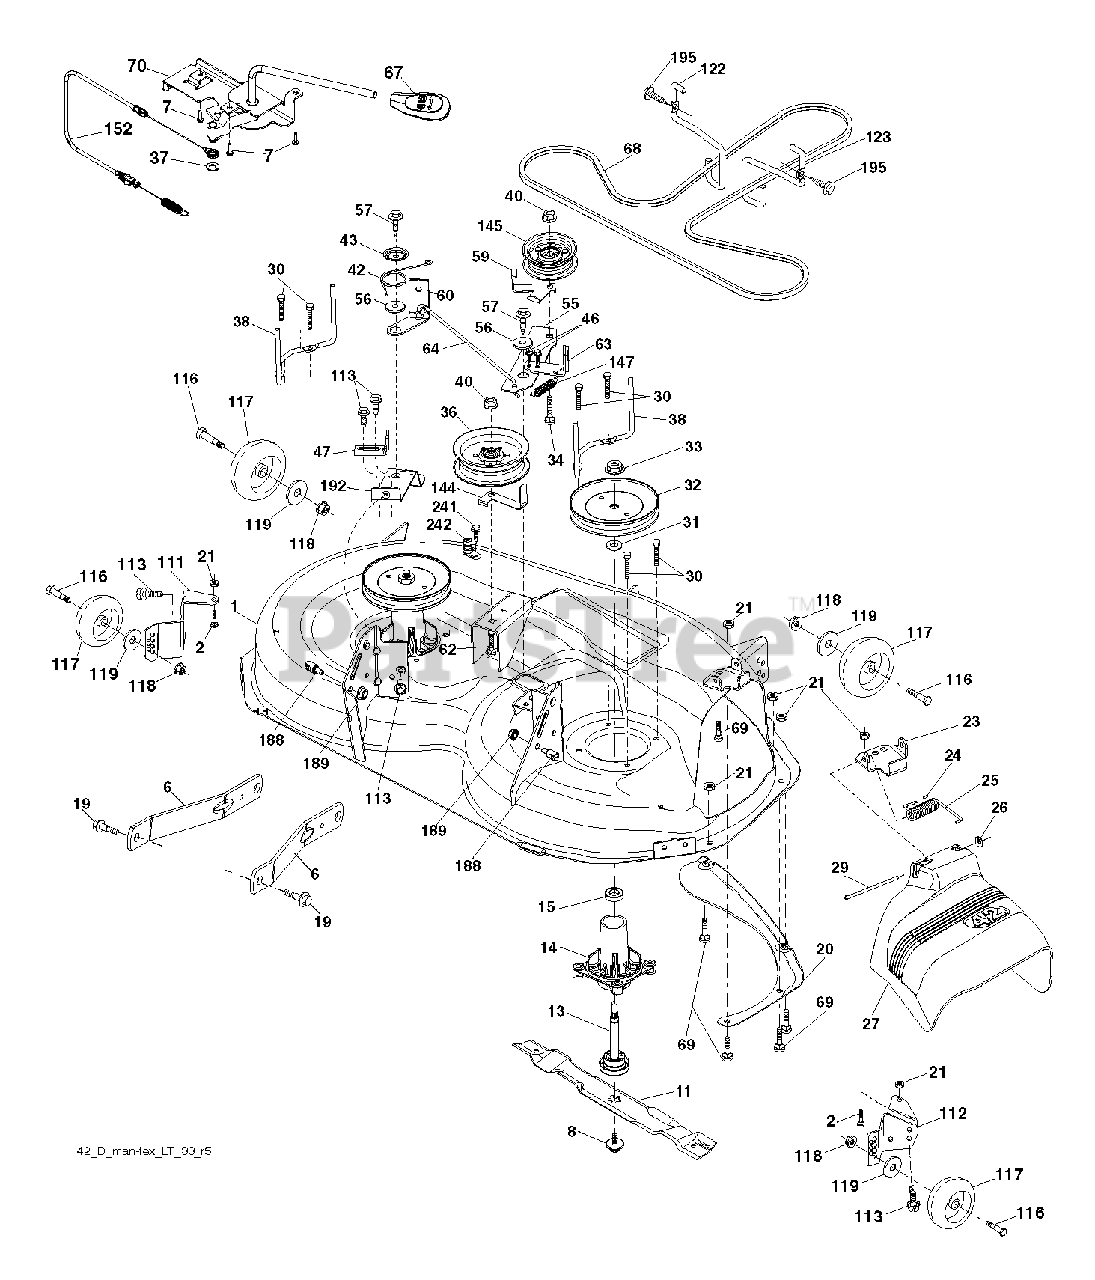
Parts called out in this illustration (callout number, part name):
2	BOLT
6	ARM.SUSPENSION.MOWER.R
7	SCREW.#10 X 0.750.BOS (2 2)
8	BOLT.WASHER.ASM.7/16-2
11	42" HI-LIFT BLADE
13	SHAFT.ASM.MDRL.N/GREASE.38
14	HOUSING.MANDREL.4PT.
19	BOLT.SHOULDER
20	BAFFLE.VORTEX
21	LOCKNUT
23	BRKT.DEFLECTOR.38"2005+
24	CAP-SLEEVE LT
25	SPRING.TORSION.DEFLECT
26	NUT PUSH M
27	SHIELD.DEFLECTOR.MOWER.42"BLAC
29	ROD.HINGE
30	SCREW, WASHER HEAD
31	WASHER.SPACER.MANDREL
32	PULLEY.MANDREL.5.438.PD
33	NUT.FLANGE.LOCK.TOP
34	BOLT.3/8-16X1.50
36	PULLEY.IDLER.2006
38	KEEPER.BELT.MANDREL.PULLEY
40	NUT LOCK FLG 3/8-16 UNC
42	SPRING.TORSION.BRAKE
43	SRPING.TORSION.RETAINE
46	SCREW.1/4-20X5/8
47	BRKT.CLUTCH.CABLE
55	IDLER.ARM.42"
56	SPACER.RETAINER
57	SCREW 3/8-16X1
59	GUARD, BELT
60	ARM BRAKE MOWER
62	BOLT
64	LINK BRAKE
67	HANDLE.CLUTCH.CABLE.LT
68	BELT.DECK.DRIVE.42"
69	BOLT
70	CLUTCH.ASM.MANUAL
111	BRKT.WHEEL.GAUGE.LH.42"
112	BRKT.WHEEL.GAUGE.RH.42"
113	BOLT.5/16HEX.WHS.HD
116	BOLT M
117	WHEEL.GAGE.HALF.SPOKED
118	LOCKNUT
119	WASHER
122	KEEPER BELT ENGINE LH
123	KEEPER BELT RH
144	KEEPER.BELT.MOWER
145	PULLEY.IDLER.48"PRIMARY
147	RETURN SPRING
152	CABLE.CLUTCH.MANUAL.
188	STUD.FASTNER.W/ANTI-ROTATE
189	NUT LOCK HEX FLANGE 5/16-18
192	BRKT.BRAKE.STAND.LH.
195	SCREW, 3/8-16X3/4
241	SCREW.TT.#10-32X.5.3/8.FLANGE
242	PORT.WASHOUT
